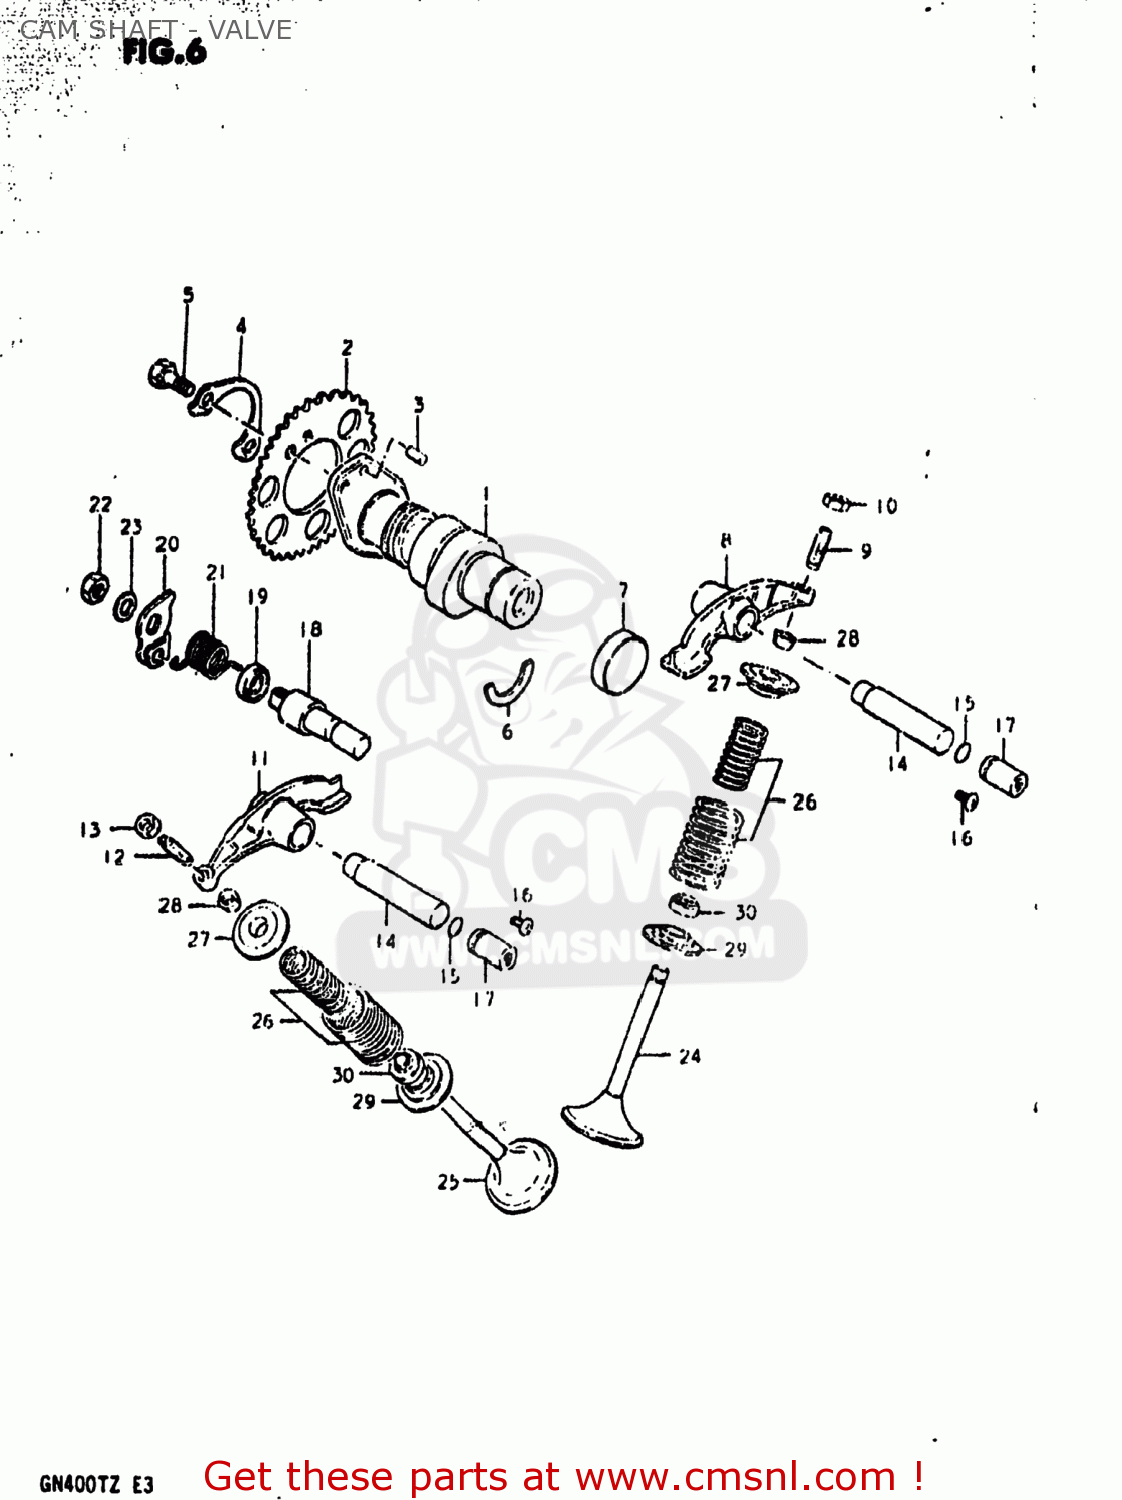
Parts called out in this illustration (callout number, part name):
1	CAMSHAFT
2	SPROCKET,CAMSHAFT
3	PIN
4	WASHER,CAM CHAIN SPROCKET
5	BOLT(6X12.5)
6	C RING
7	PLUG
8	ARM,VALVE ROCKER
9	SCREW,TAPPET ADJUSTING
10	NUT,ADJUSTING SCREW
11	ARM,VALVE ROCKER
12	SCREW,TAPPET ADJUSTING
13	NUT,ADJUSTING SCREW
14	SHAFT,VALVE ROCKER
15	O-RING
16	SCREW
17	CAP,ROCKER ARM SHAFT
18	SHAFT,DECOMPRESSION
19	OIL SEAL
20	LEVER,DECOMPRESSION SHAFT
21	SPRING
22	NUT 8MM
23	WASHER
24	VALVE,INTAKE
25	VALVE,EXHAUST
26	SPRING SET,VALVE
27	RETAINER,VALVE SPRING
28	COTTER VALVE
29	SEAT,VALVE SPRING
30	SEAL,OIL(7X14.4X9)
